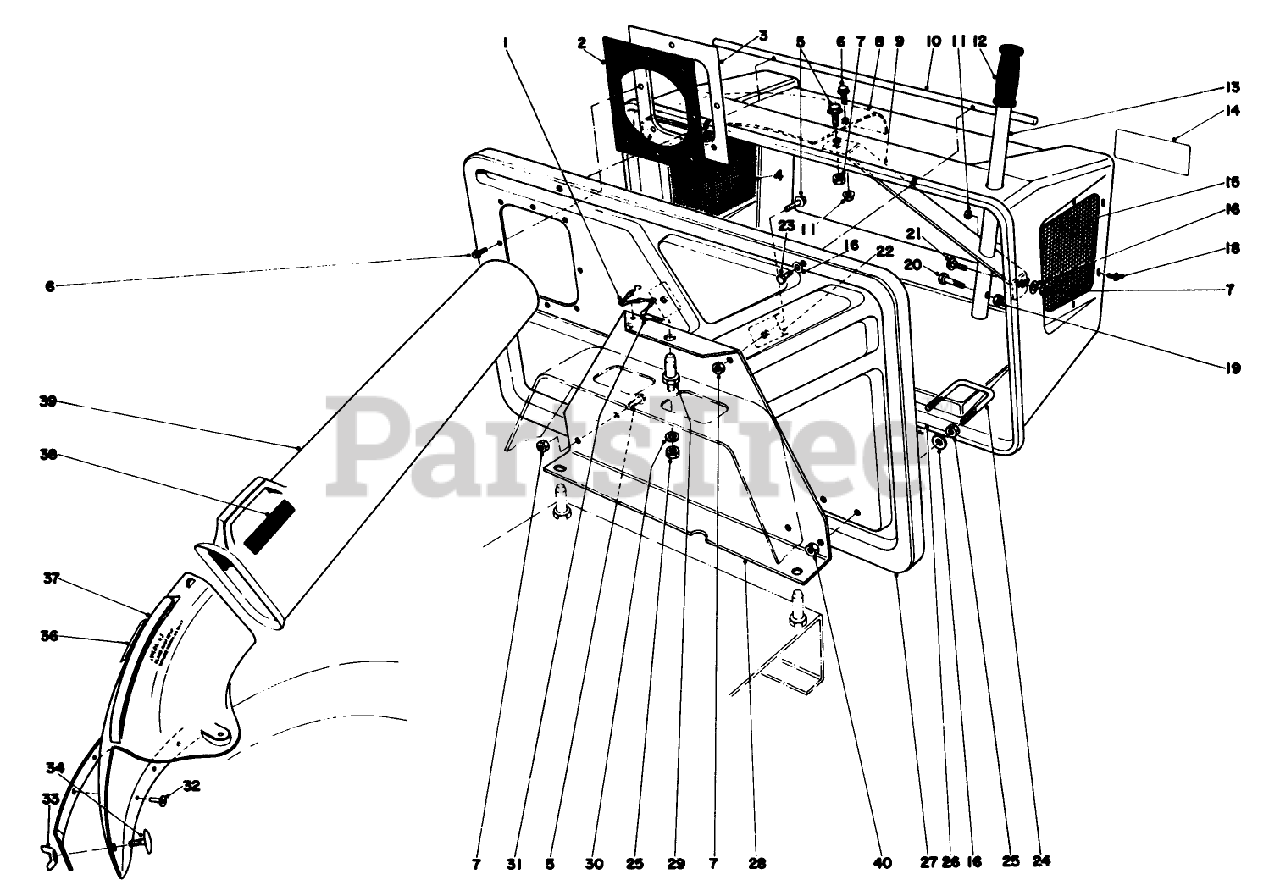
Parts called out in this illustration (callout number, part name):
4	Screen
5	SCREW-HHF
6	SCREW
7	NUT-HEX, SIDE DEFORM
8	DEFLECTOR
9	HANDLE GUIDE
10	PIVOT ROD
11	NUT-LOCK, FLANGE
13	HANDLE TUBE
15	SCREEN
16	WASHER-FLAT
18	SCREW-HWH
19	NUT-HEX, SIDE DEFORM
20	SCREW-HH
21	SCREW-CARR
23	SCREW-HH
24	LATCH
25	NUT-HEX
26	HOPPER
30	WASHER-LOCK
33	NUT-WING
39	DUCT ASM
40	NUT-LOCK, NI
